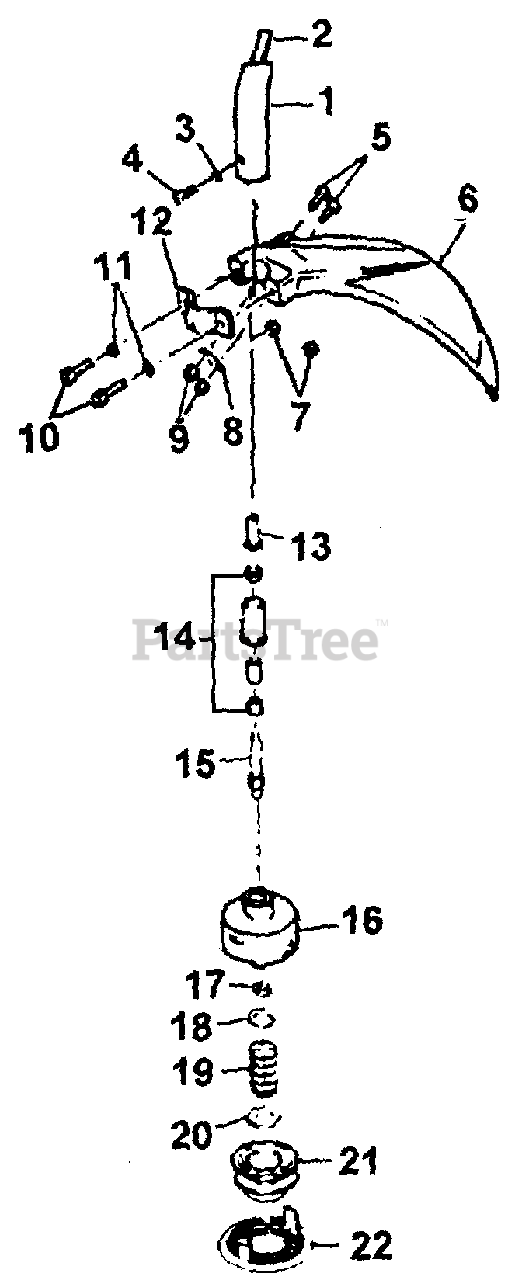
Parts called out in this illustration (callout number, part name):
1	TUBE ASSY.
2	FLEX CABLE
4	SCREW
5	SCREW
6	DEFLECTOR
7	NUT
8	BLADE, CUT-OFF
9	NUT
10	SCREW
12	BRACKET CLAMP
13	ADAPTER, ARBOR
14	BUSHING ASSY.
15	ARBOR POST
16	3" HEAD BODY
18	PLATE, SPRING
20	PLATE, SPRING
22	3" HEAD CAP
